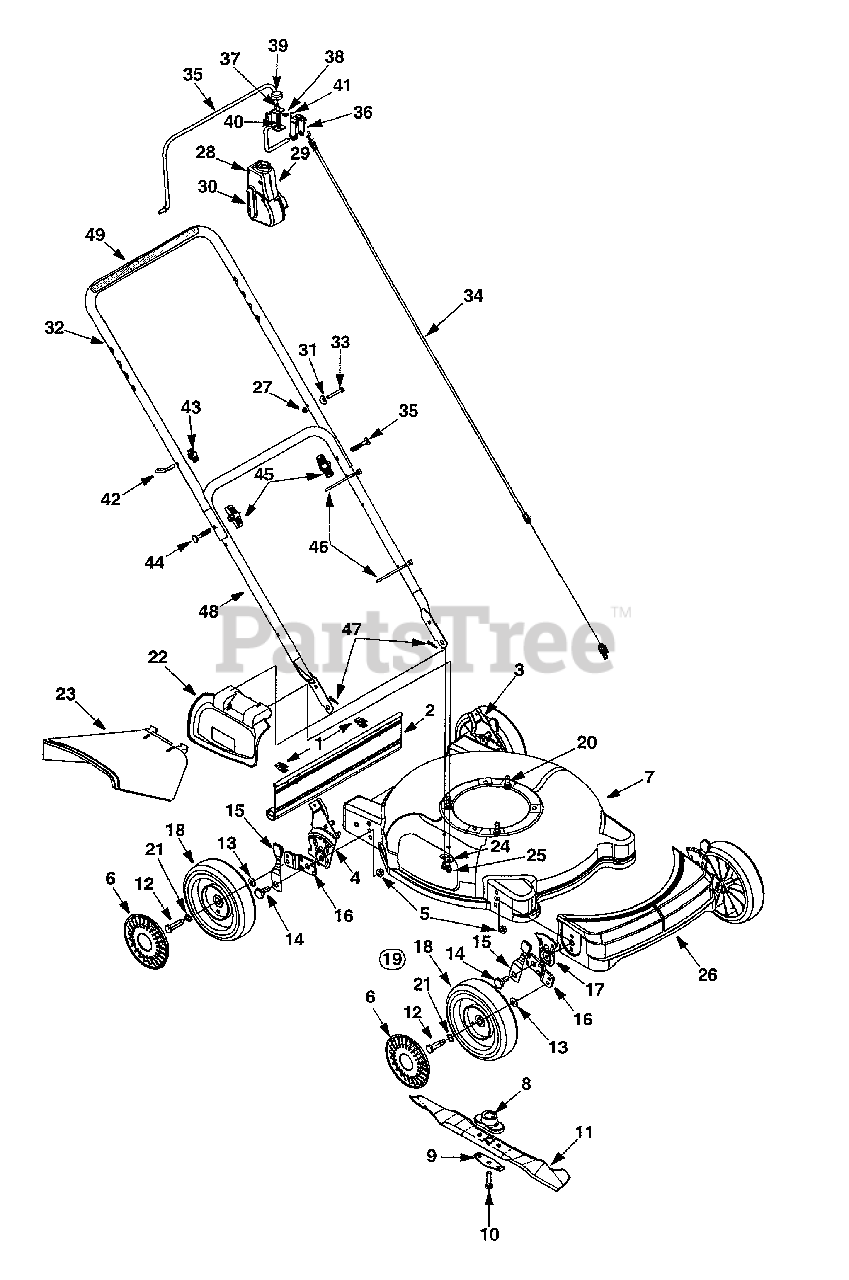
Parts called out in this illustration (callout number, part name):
1	Hinge Clip
2	Rear Flap
5	Flange Lock Nut 3/8-16
6	Hub Cap-Yellow
9	Blade Bell Support
10	Hex Bolt 7/16-20 x .88"
11	20" Mulch Blade
12	Axle Bolt
13	Bell Washer .400" ID x .88"
14	Shoulder Bolt
15	Spring Lever Ass'y w/Knob
17	Height Adj. Plate
18	Wheel Assembly
19	Height Adj. Ass'y Comp.
20	Hex Lock Wash. Hd. Screw
21	Wave Washer
22	Mulching Plug
23	Chute Deflector
24	Bell Washer
25	Hex Wash. Hd. Tf Screw 1/4-20 x .5" Lg.
26	Cover: Front End
27	Hex Lock Nut 1/4-20 Gr. 8
28	Hi-Low Screw
29	Control Cover LH
30	Control Cover RH
31	Saddle Washer
34	Control Cable 56.75" Lg.
38	Retention Ring
39	Button
40	Compression Spring
41	Torsion Spring
42	Rope Guide
43	Handle Knob
44	Carriage Bolt
45	Hand Knob
46	Cable Tie
47	Hairpin Clip
49	Foam Grip
